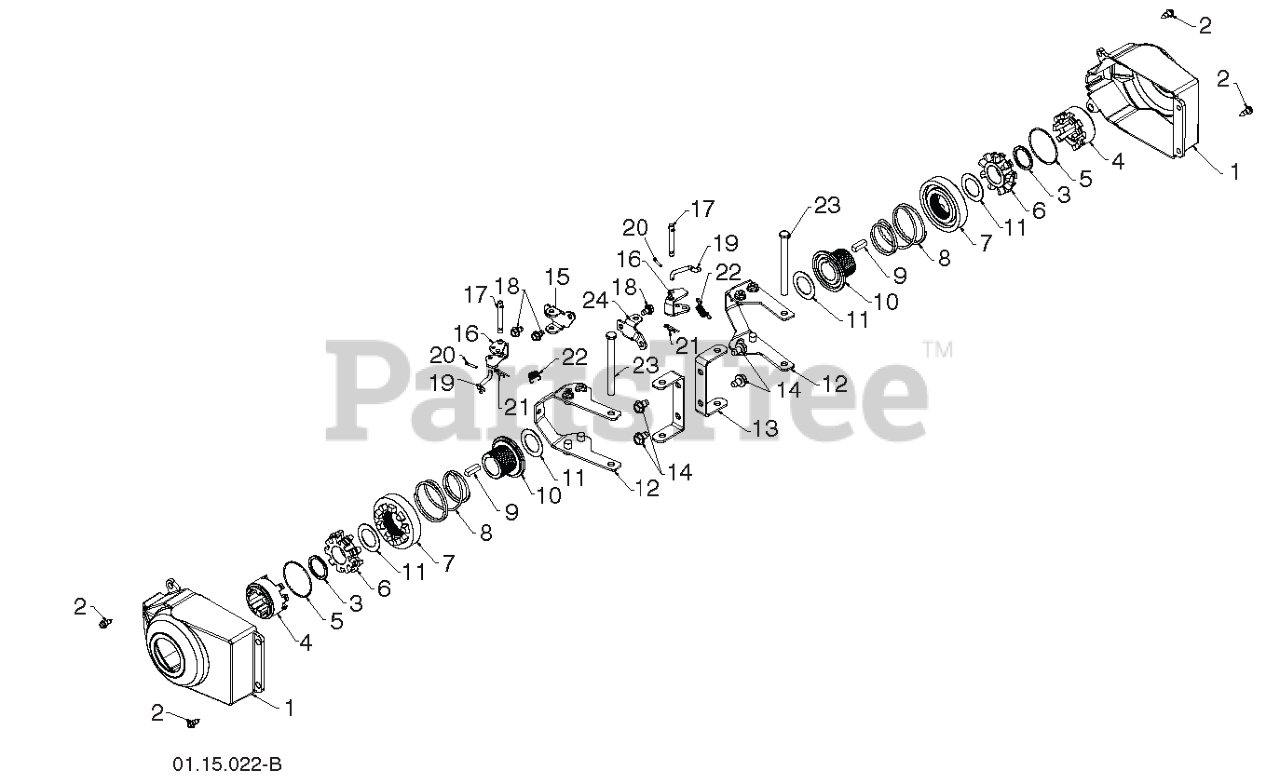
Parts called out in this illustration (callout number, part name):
1	COVER, POWER STEERING
2	SCREW, HEX HEAD, TAPPING
3	SPACER.POWER.STEERING TRACK
4	DRIVER.WHEEL.POWER.STEERING
5	RING, WIRE RETAINER
6	LOBE WHEEL
7	SLIDE.CLUTCH.SNOW
8	SPRING COMPRESSION TAPERED.PS
9	KEY, SQUARE 1/4 X .875
11	WASHER 1.00
12	YOKE.ASM.BOLT.BLACK
13	BRACKET.STEER.PNT.BLACK
14	Screw 5/16-18 x 1/2 Hex, Self Tapping 5/16-18 x 1/2
15	BRKT.STEER.PIVOT.RH
16	BELLCRANK.STEER
17	PIN, STEERING BELLCRANK
18	SCREW 1/4X20
19	LINK.STEER.YOKE
20	RETAINER CLIP
21	RETAINER CLIP PM
22	SPRING LATCH
23	PIN, STEERING LEVER
24	BRACKET.STEER.PIVOT.LH.YZ
